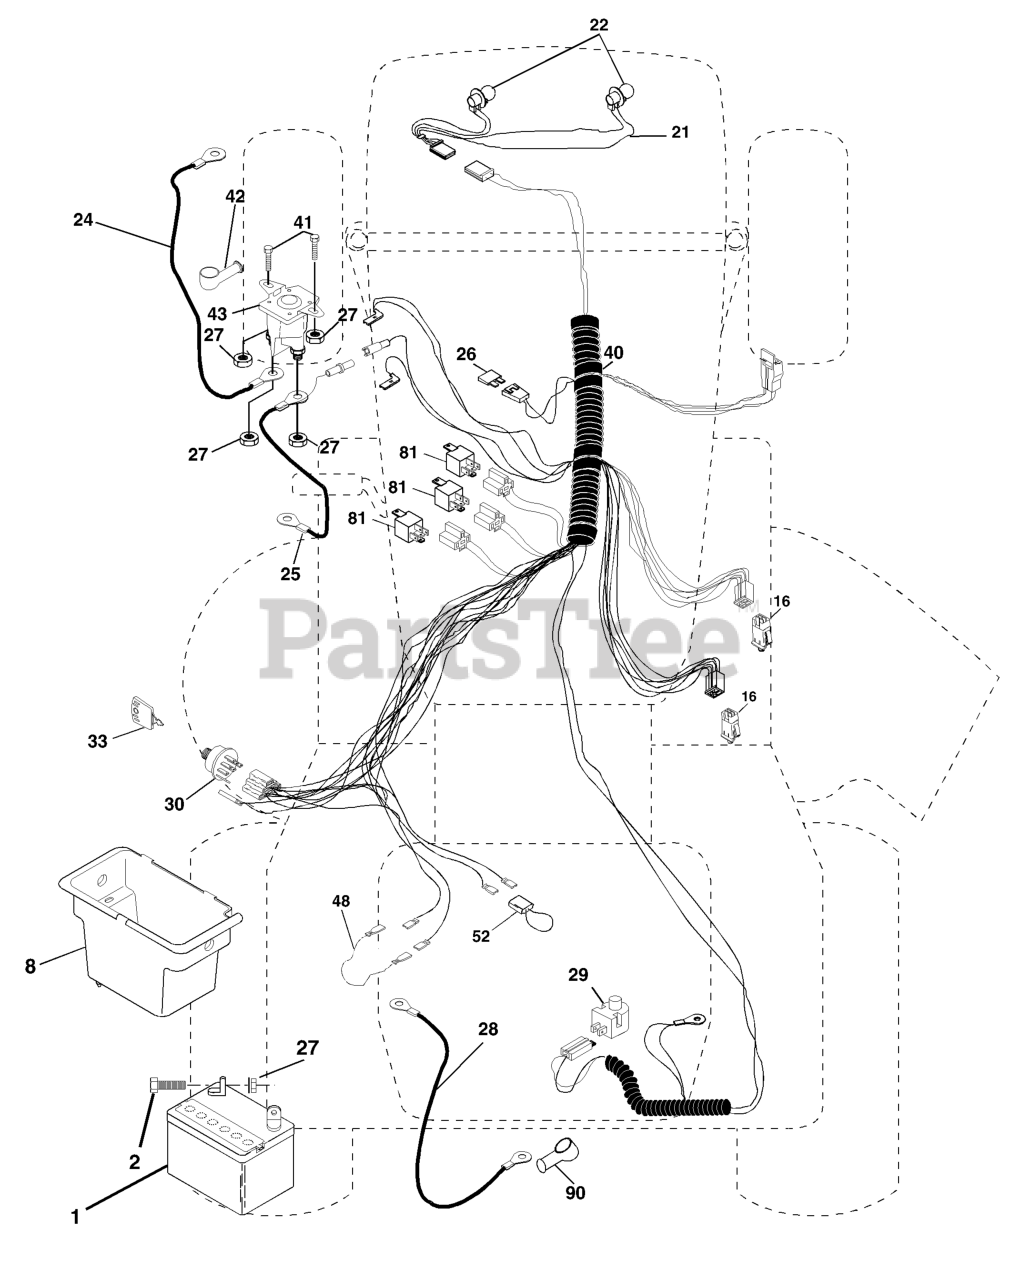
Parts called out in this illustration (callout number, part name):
1	Battery
2	BOLT.HEX.1/4.X.3/4.DICHROMATE
8	BOX.BATTERY.FENDER
16	INTERLOCK SWITCH
21	HARNESS.ASM.LIGHT WSL
24	BATTERY CABLE GT
25	CABLE BATTERY
26	FUSE 20AMP
27	NUT
28	CABLE T
29	PLUNGER SWITCH (COLOR:OLIVE)
30	IGNITION SWITCH
33	KEY MLD GEN DELTA
40	HARNESS.IGNITION.KOHL
41	BOLT
42	TERMINAL COVER
43	SOLENOID
48	ADAPTER.AMMETER
52	WIRE PROTECTION LOOP
81	RELAY.ASSY.T
90	COVER TERMINAL
